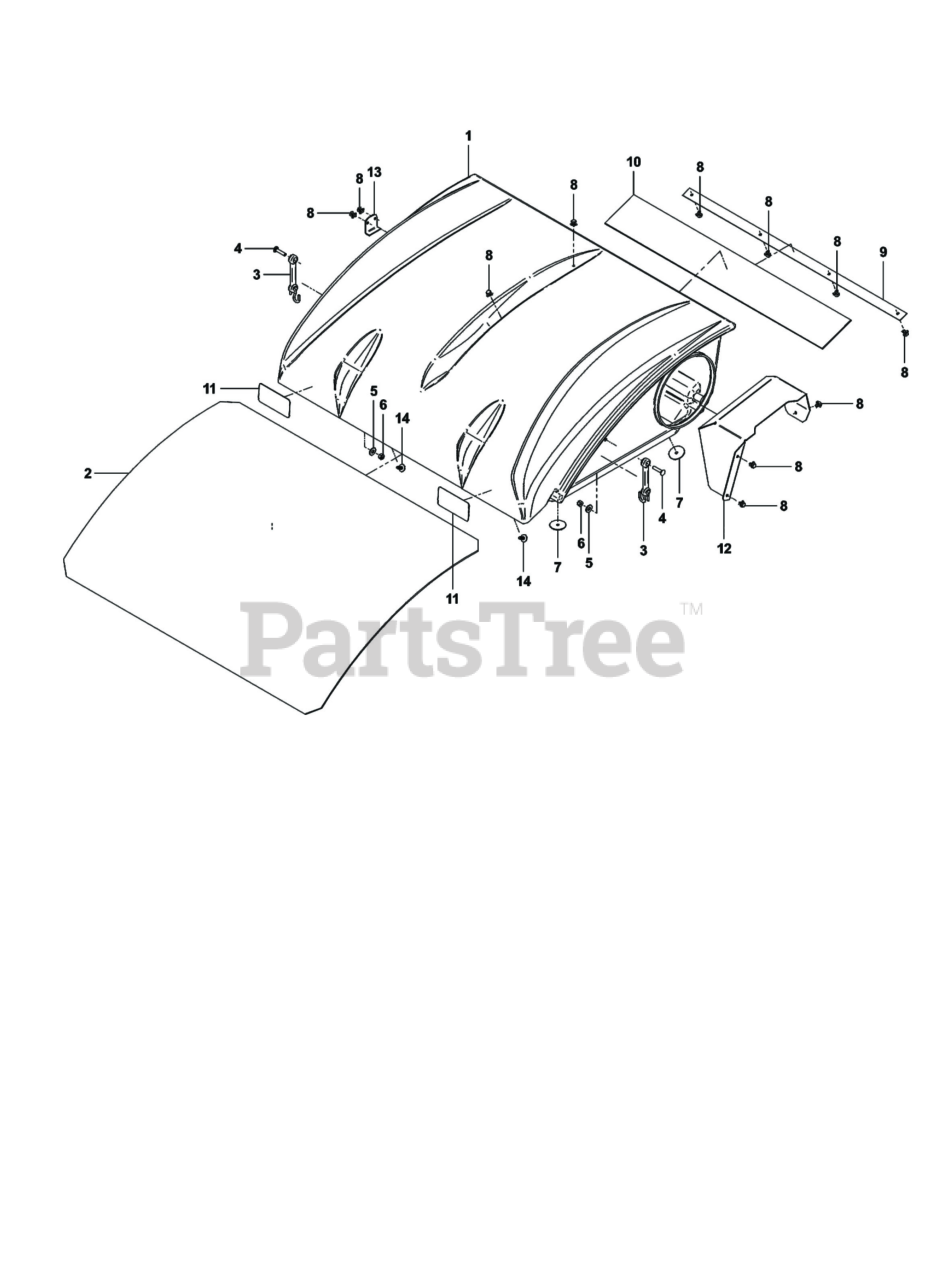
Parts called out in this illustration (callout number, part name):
1	PRO 2 BAGGER TOP (GEN2)
3	RUBBER STRAP W/HOOKS
4	BOLT-1/4-20 x 1-1/
5	FLAT WASHER
6	NUT-NYLOCK 1/4-20
7	WASHER-FENDER 3/16
8	RIVET-PLASTIC 5MM
9	DUST GUARD BRACE
10	RUBBER SEAL
11	LABEL-2 x 4 RED RE
12	GRASS DEFLECTOR
13	HINGE STOP PLATE
14	FLAT HEAD FASTENER
